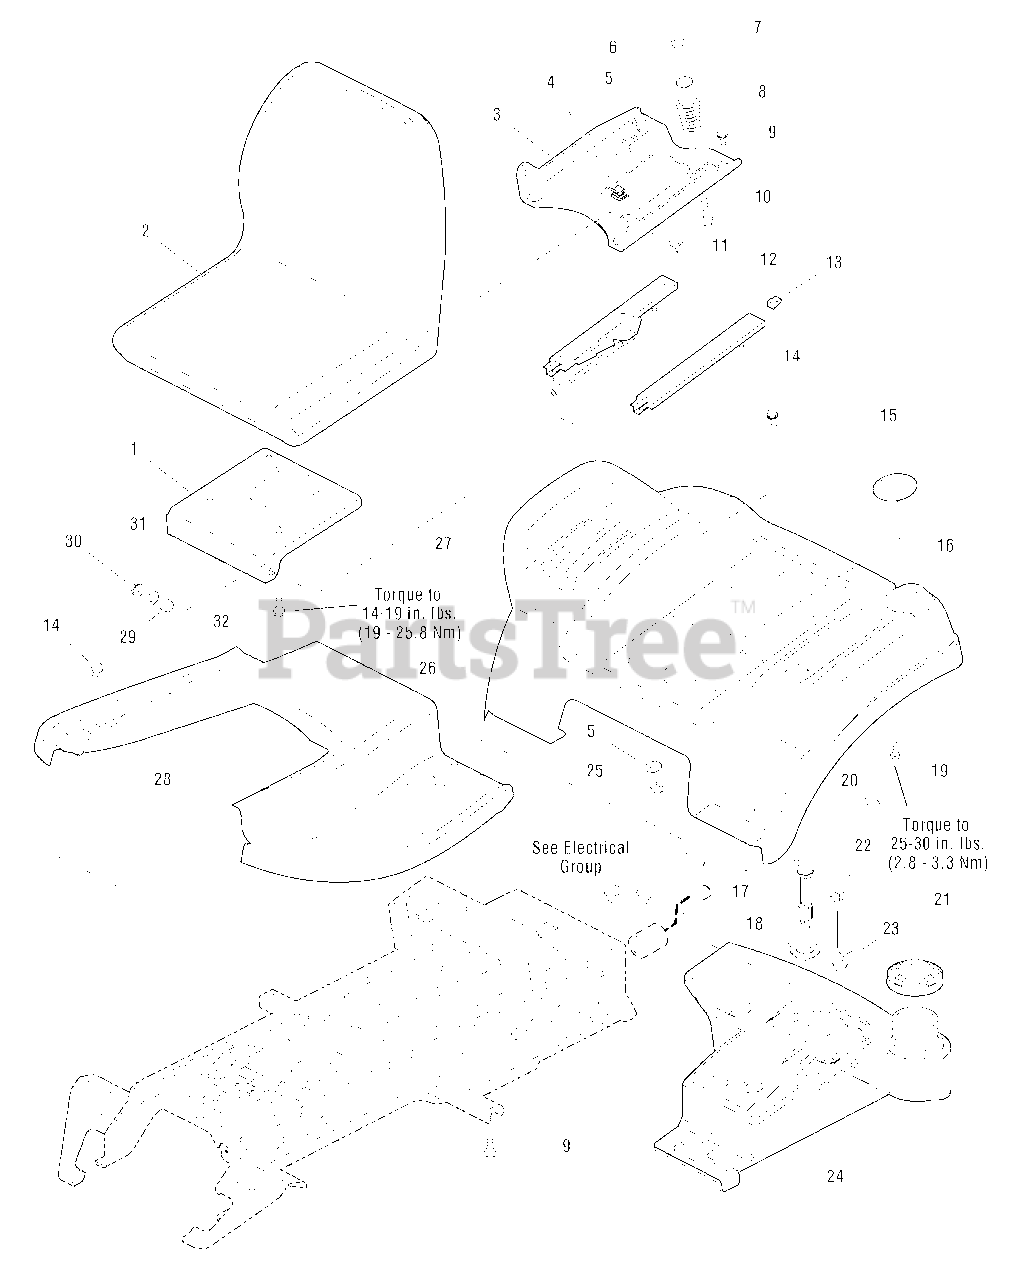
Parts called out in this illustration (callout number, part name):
1	BRACKET, 1-5/8 x 1-3/4
2	* SEAT, 15" Back, Standard
3	SUPPORT, Seat
4	CLIP, Wire
5	WASHER, Spring, 5/16 x 1-1/4, Black
6	SPRING, Compression
7	NUT, Hex Lock ESNA Light, 5/16-18
8	SPRING, Compression
9	CAPSCREW, Hex Flange Whiz Lock, 5/16-18 x 3/4
10	CARRIAGE BOLT, 5/16-18 x 2
11	CARRIAGE BOLT, 3/8-16 x 1
12	SLIDE, Seat
13	NUT, Speed, Lug Type, 5/16-18
14	CAPSCREW, Hex Washer Head Taptite, 5/16-18 x 5/8
15	PLUG, Plastic
16	POD, with Cup Holder, LH
17	FUEL GAUGE
18	GROMMET
19	CAPSCREW, Hex Head Dog Point, 1/4-20 x 7/8
20	NUT, Hex Flange Whiz Lock, 5/16-18
21	CAP, Gas
22	TUBE & ELBOW ASSEMBLY
23	BUSHING, 3/8 x 9/16 x 5/8, Rubber
24	TANK, Fuel
25	NUT, Hex KEPS, 5/16-18
26	DECK, Seat, Orange
26	DECK, Seat, Red
27	POD, RH with 2 Slots
28	TUNNEL, Orange
28	TUNNEL, Red
29	SPACER, 25/64 x 5/8 x 3/16, Hardened
30	NUT, Hex Flange Two-Way Lock, 3/8-16
31	WASHER, 3/8
32	CAPSCREW, Hex Flange Whiz Lock Dog Point, 5/16-18 x 1
